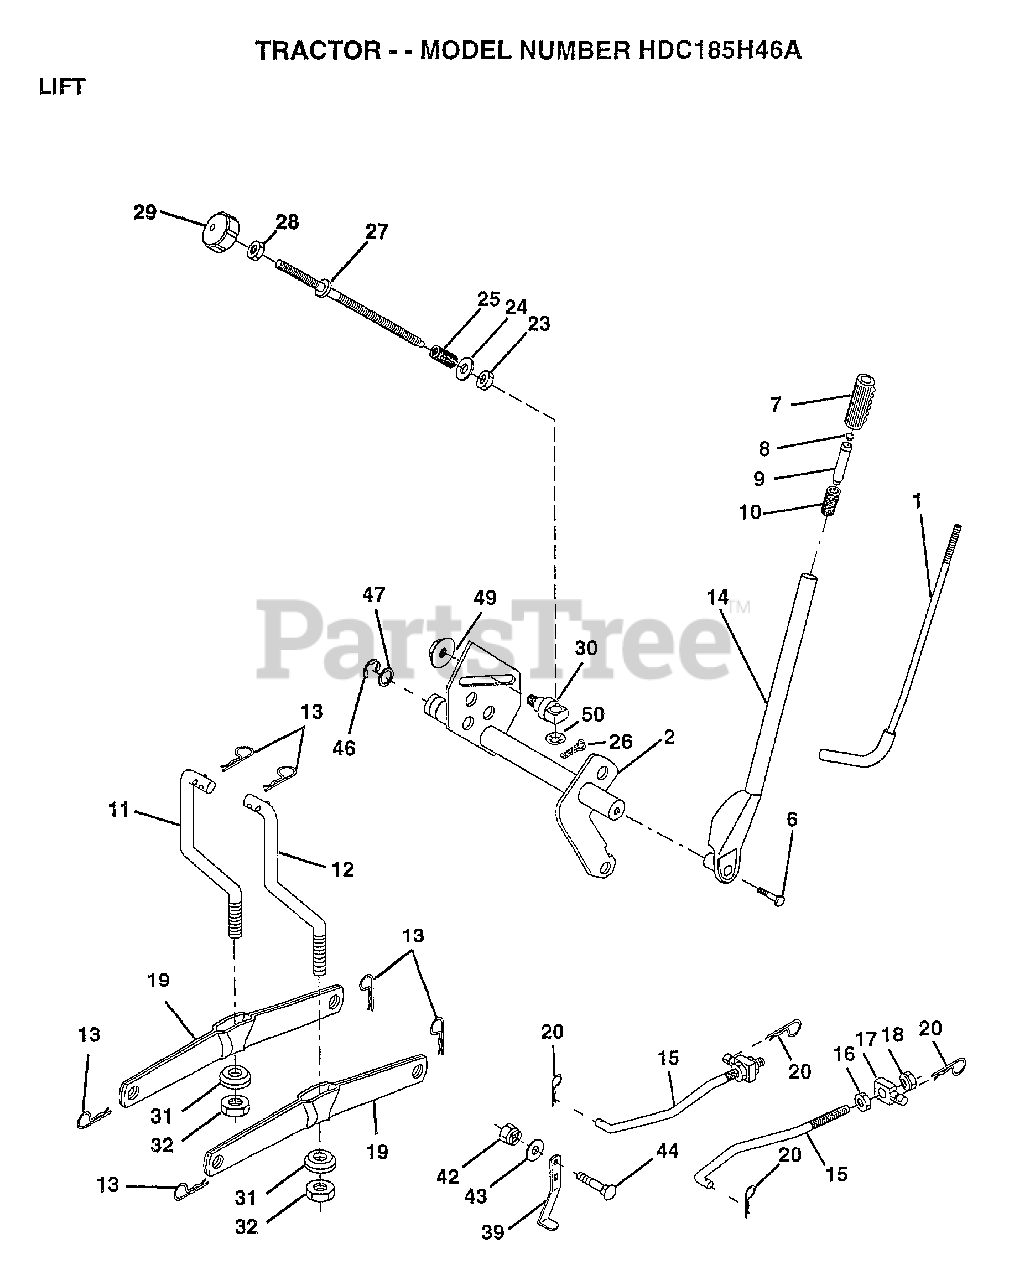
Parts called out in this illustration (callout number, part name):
1	LEVER ROD LT
2	SHAFT LIFT W/IND
6	"BOLT,HEX"
7	GRIP
10	SPRING T
11	LINK.LIFT.LH.GTV
12	LINK.LIFT.RH.GTV.
15	LINK.FRONT
16	NUT
17	TRUNION
18	NUT.LK.W/WSH.1/2.
19	ARM SUSP REAR
20	RETAINER.SPRING
23	NUT T
24	WASHER
25	SPRING T
26	PIN, COTTER 3/32 X 1/2
28	NUT
29	KNOB INF 3/8-16
30	TRUNNION
31	BEARING PVT LH
32	NUT.CROWNLOCK.3/8
39	STOP.OVER.CENTER
43	WASHER GT
44	BOLT
46	E-RING
47	WASHER
49	NUT.HXFLG.LOCK.
50	NUT PUSH M
